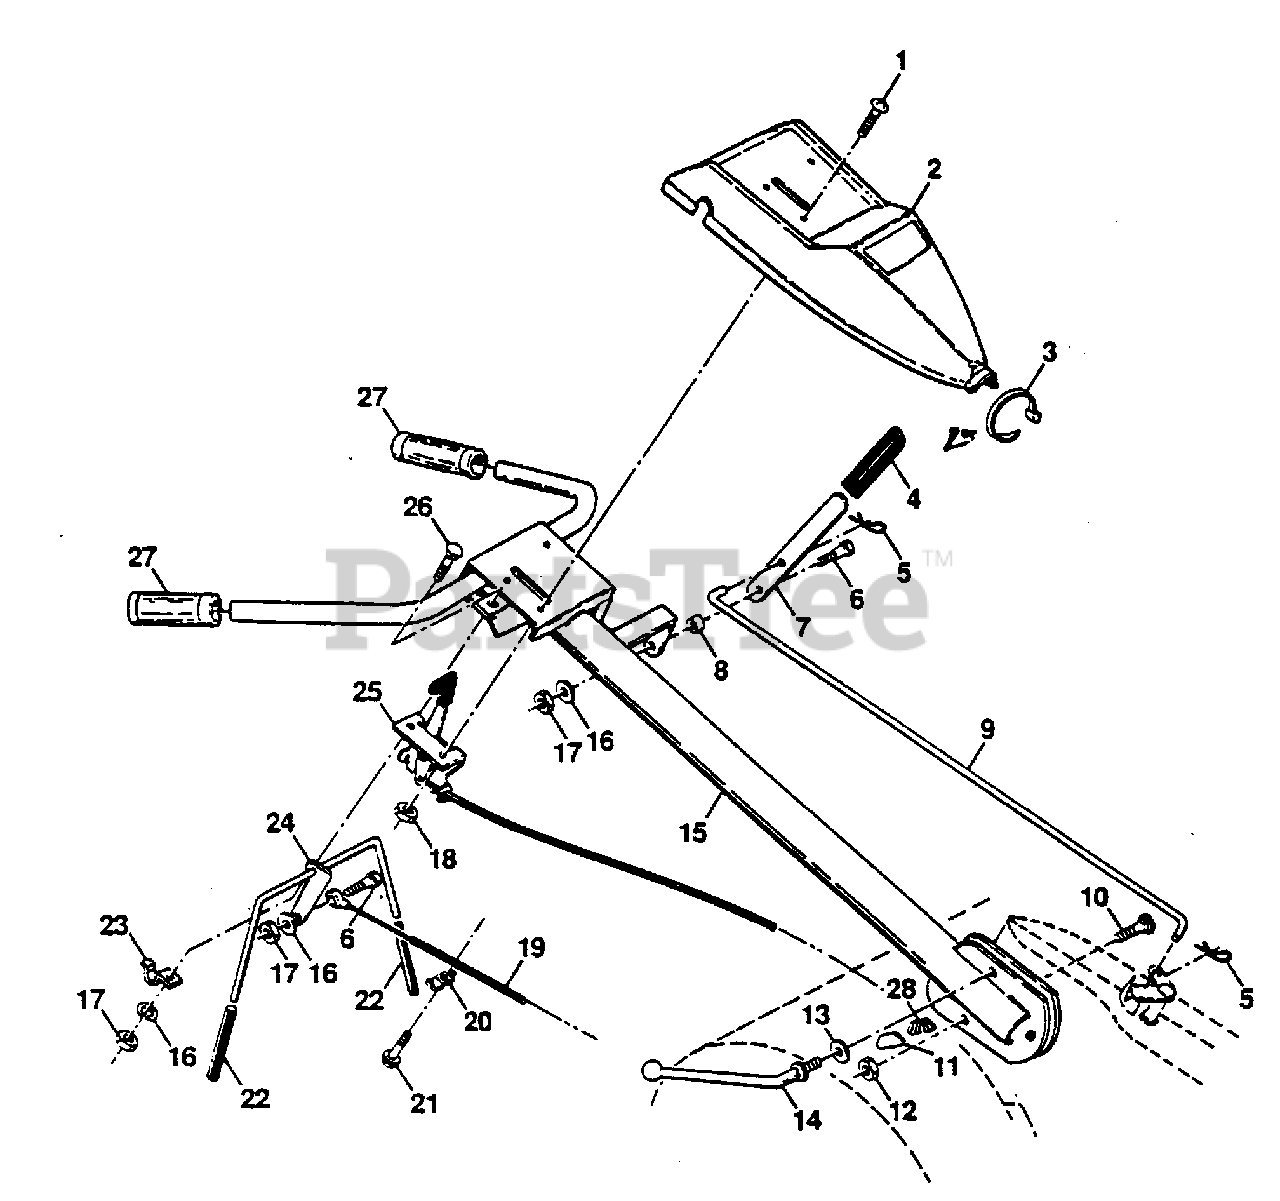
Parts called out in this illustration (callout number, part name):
1	Screw, Pan Hd. #10-24 UNC (AYP part number)
2	Panel, Control (AYP part number)
3	Tie, Cable (AYP part number)
4	Grip, Handle (AYP part number)
5	Clip, Hairpin (AYP part number)
6	Bolt, Shoulder (AYP part number)
7	Handle, Shift (AYP part number)
8	Grommet, Rubber (AYP part number)
9	Rod, Shift (AYP part number)
10	Bolt, Carriage 3/8-16 x 1 (AYP part number)
11	Lock, Handle (AYP part number)
12	Nut, Centerlock 3/8-16 (AYP part number)
13	Washer 13/32 x 1 x 11 Ga. (AYP part number)
14	Lever, Lock, Handle (AYP part number)
15	Handle (AYP part number)
16	Washer, Lock 1/4 (AYP part number)
17	Nut, Hex 1/4-20 (AYP part number)
18	Nut, Keps #10-24 UNC (AYP part number)
19	Cable, Clutch (AYP part number)
20	Clip (AYP part number)
21	Screw, Hex Washer Hd. Slotted #10-24 x 1/2 (AYP part number)
22	Grip, Bar, Control (AYP part number)
23	Clamp, Bar, Control (AYP part number)
24	Bar Assembly, Control (AYP part number)
25	Control, Throttle (AYP part number)
26	Bolt, Carriage 1/4-20 UNC x 1/2 (AYP part number)
27	Grip, Handle (AYP part number)
28	Lock, Handle (AYP part number)
